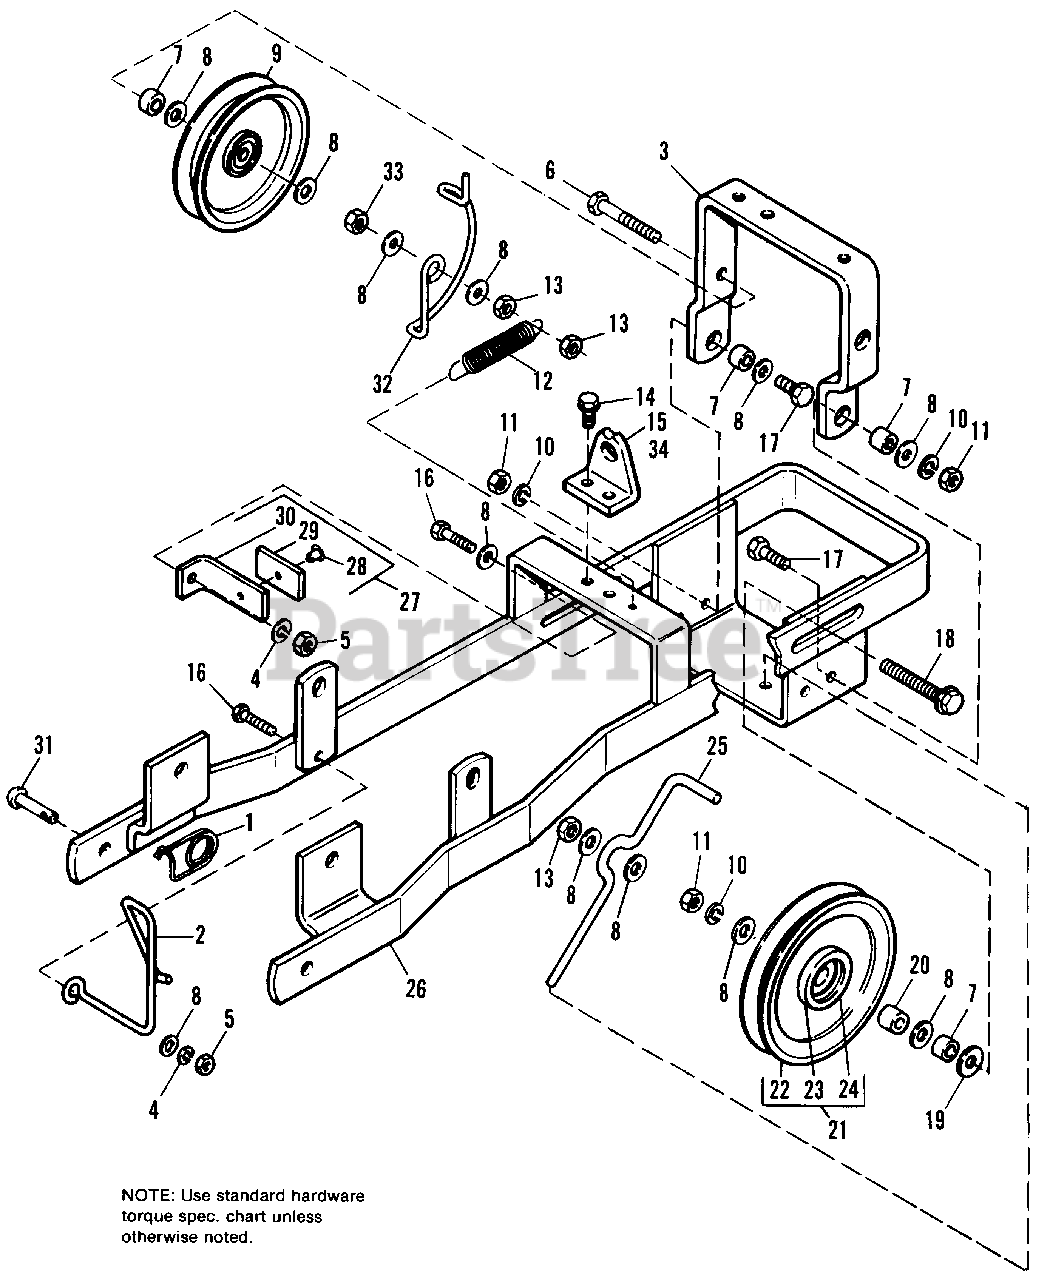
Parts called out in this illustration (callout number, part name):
1	CLIP, Spring
3	PIVOT, Bracket
4	LOCKWASHER, 5/16
5	NUT, Hex, 5/16-18
6	CAPSCREW, Hex, Full Thread, 3/8-16 x 2-1/2
8	WASHER, Plain, 5/16
10	LOCKWASHER, 3/8
11	NUT, Hex, 3/8-16
12	SPRING
13	LOCKNUT, Hex, Jam, 3/8-16
14	SCREW, Taptite, 5/16-18 x 3/4
15	PIVOT, (All except 6000)
16	CAPSCREW, hex, 5/16-18 x 1-1/4
17	CAPSCREW, Hex, 3/8-16 x 1-1/4
18	SCREW, Whizlock, 3/8-16 x 3
19	WASHER, Plain, 13/32 x 1
21	PULLEY ASSY., w/Bearing (Incl. Ref. Nos.22,23, 24)
23	RING, Retaining
26	PUSH BAR ASSY.
27	BRAKE BRACKET ASSY. (Incl. Ref. Nos. 28, 29, 30)
30	BRACKET, Brake
33	NUT, Hex, Jam, 3/8-16
34	SUPPORT, Hitch, Rear (6000 Series only)
